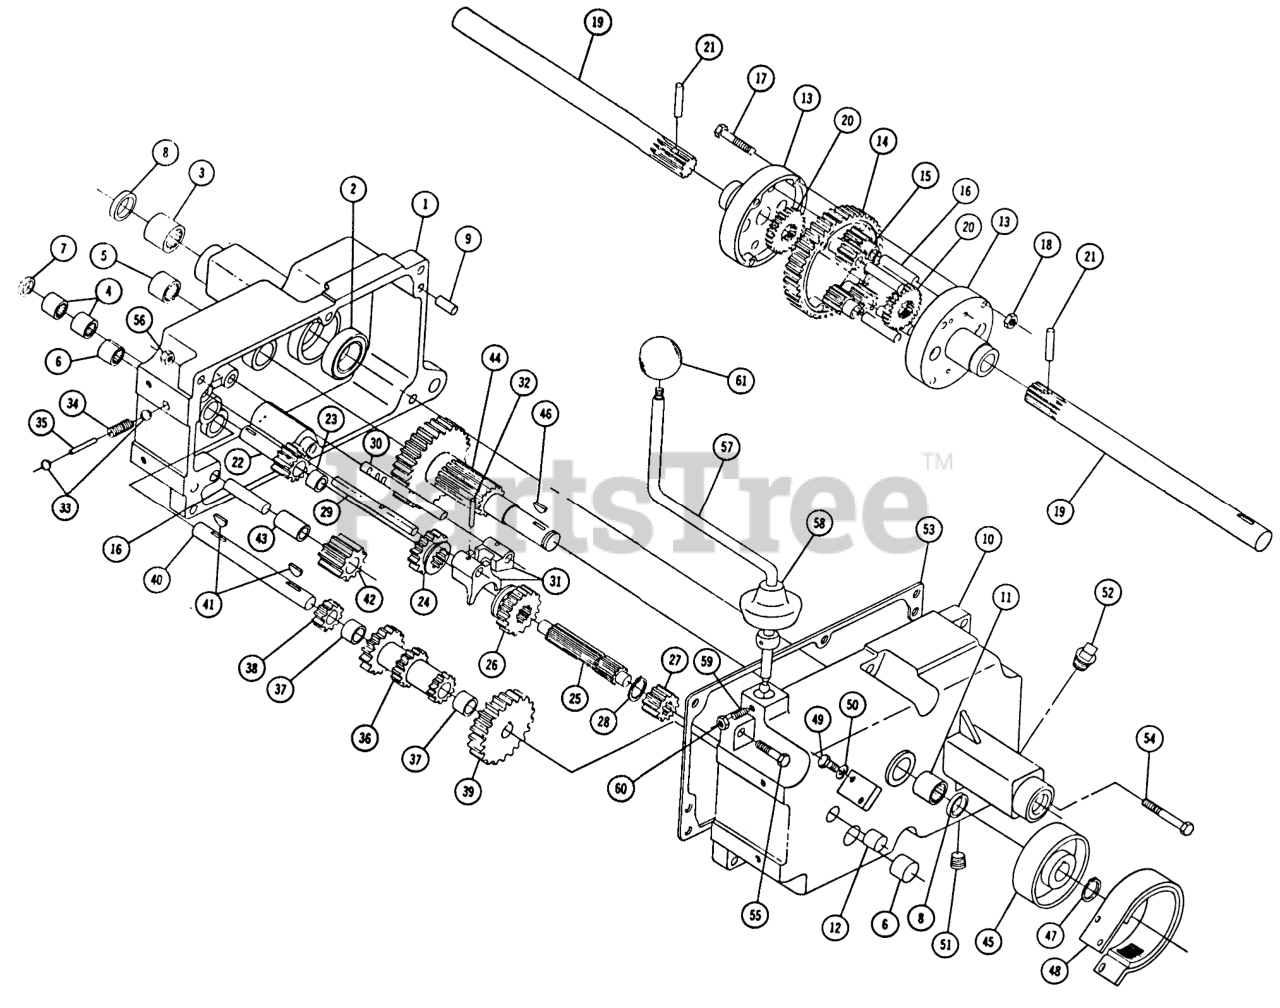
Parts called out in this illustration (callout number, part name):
3	BEARING-NEEDLE
5	BEARING-NEEDLE
6	BEARING-NEEDLE
9	PIN-DOWEL
13	DIFFERENTIAL CASE
14	SVC BULLT 394
16	PIN-DIFFERENTIAL
20	AXLE GEAR
23	BEARING-NEEDLE
27	GEAR
29	RAIL-SHIFT
30	RAIL-REAR SHIFT
31	FORK-SHIFT
32	PIN-ROLL
33	BALL-DETENT
34	Wheel Hub 105762
35	PIN-SHIFT
37	BUSHING-BRONZE
39	GEAR-CLUSTER SHAFT
41	Key
42	GEAR/BUSHING ASM-REVERSE IDLER
43	BUSHING
46	KEY-WOODRUFF
48	BRAKE BAND & LINER A
49	Bolt-1/4-20 x 5/8
50	Lockwasher
53	GASKET-TRANSMISSION
54	Bolt Hex 3/8-16 x 1
55	Bolt, 3/8 16 x 2
57	Stick-Ship Ass-y.
58	COVER-DUST
59	SETSCREW
60	Nut-Nylok
61	Knob
